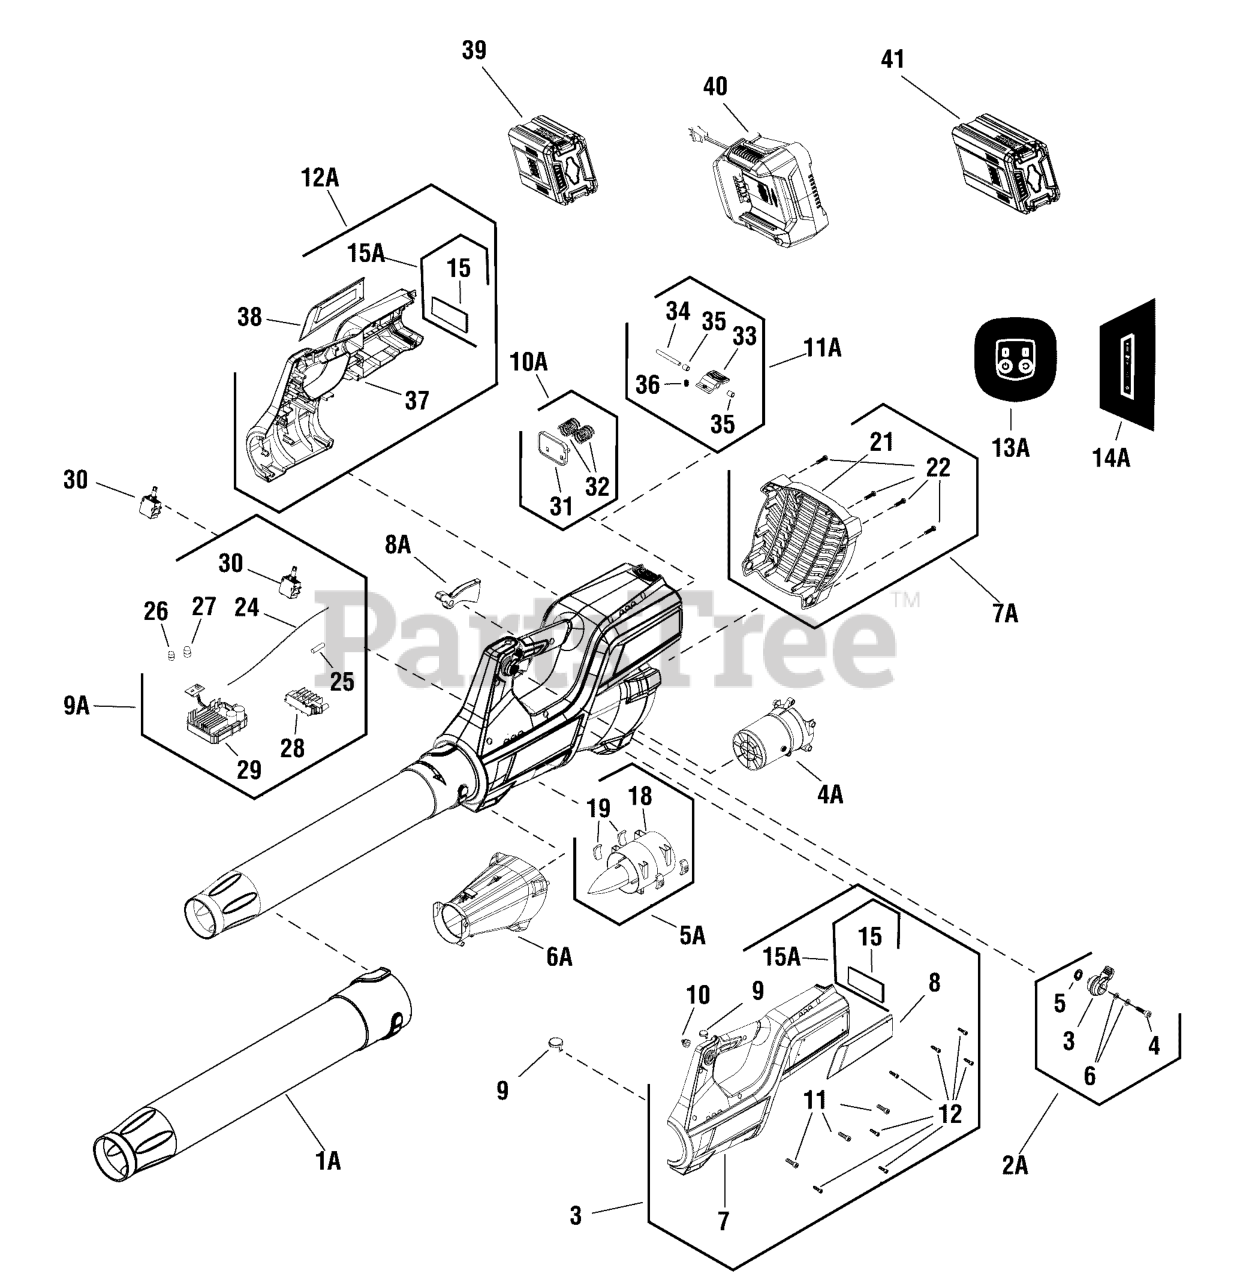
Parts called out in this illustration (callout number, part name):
1A	TUBE ASSEMBLY
2A	SWITCH ASSEMBLY
3	KIT, LEFT HANDLE, NA
4	SCREW
4A	TUBE, CONNECTING
5	WASHER, Spring
5A	KIT. MOTOR
6	PAD
6A	TUBE, AIR INLET
7	HANDLE, Left
7A	KIT, INLET GUARD
8	COVER, LEFT DECORATIVE
8A	KIT, SWITCH, TRIGGER
9	BUTTON, Start
9A	KIT, PCB
10	NUT
10A	KIT, BASE SPRING
11	SCREW
11A	KIT, BATTERY RELEASE BUTTON
12	SCREW
12A	KIT, RIGHT HANDLE
13A	DECAL, SPEED
14A	DECAL, Charger
15	PROTECTIVE COVER DECAL, CLEAR
15A	KIT, PROTECTIVE COVER DECAL, CLEAR
18	MOTOR
19	SPONGE
21	GUARD, INLET
22	SCREW
25	SHRINK TUBE
26	TERMINAL
27	TERMINAL
28	INSERT
29	BOARD, CIRCUIT
31	SPRING SEAT
32	COMPRESSED SPRING
33	BUTTON, Battery Releasee
34	PIN. ROLL
35	COVER
36	SPRING
37	HANDLE, RIGHT
38	COVER, DECORATIVE
39	* BATTERY, 2.0, 82V NA
40	* CHARGER, Battery, NA
41	* BATTERY, 4.0, 82V NA
